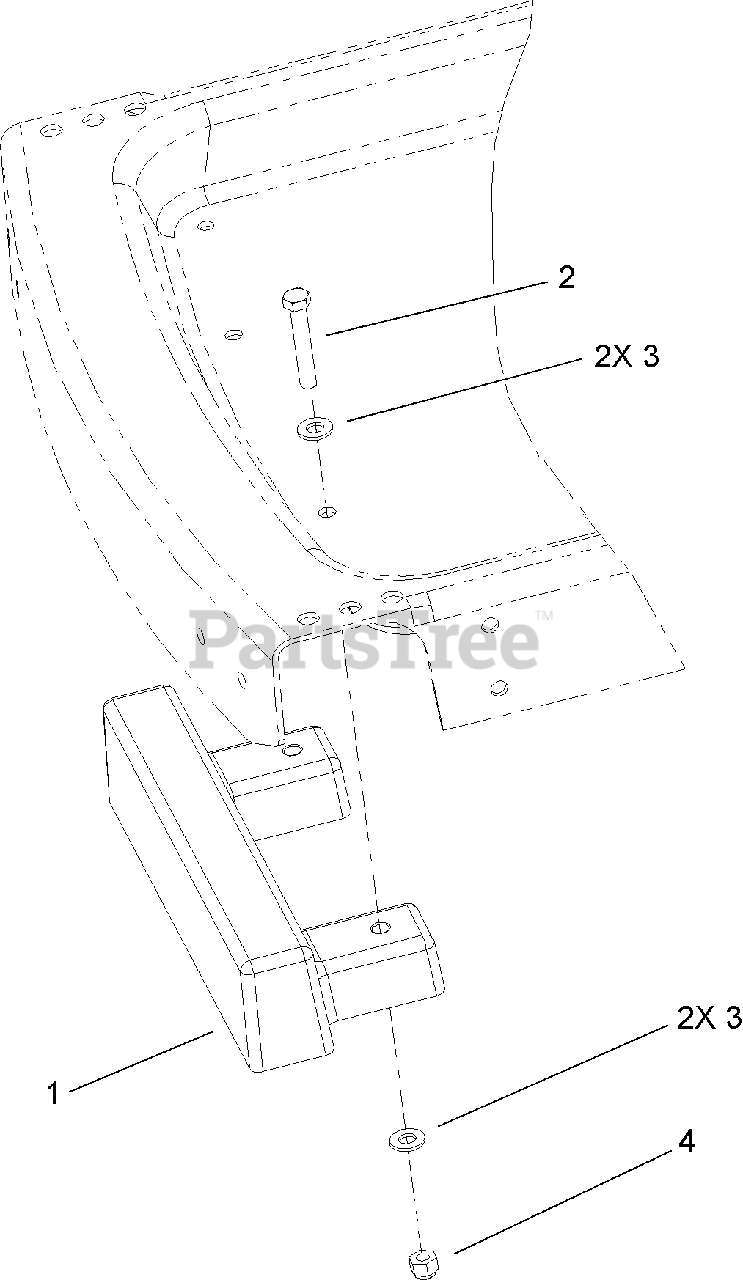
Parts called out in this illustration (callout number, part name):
1	WEIGHT-BAGGER
2	SCREW-HH
3	WASHER-FLAT
4	NUT-LOCK, NI
